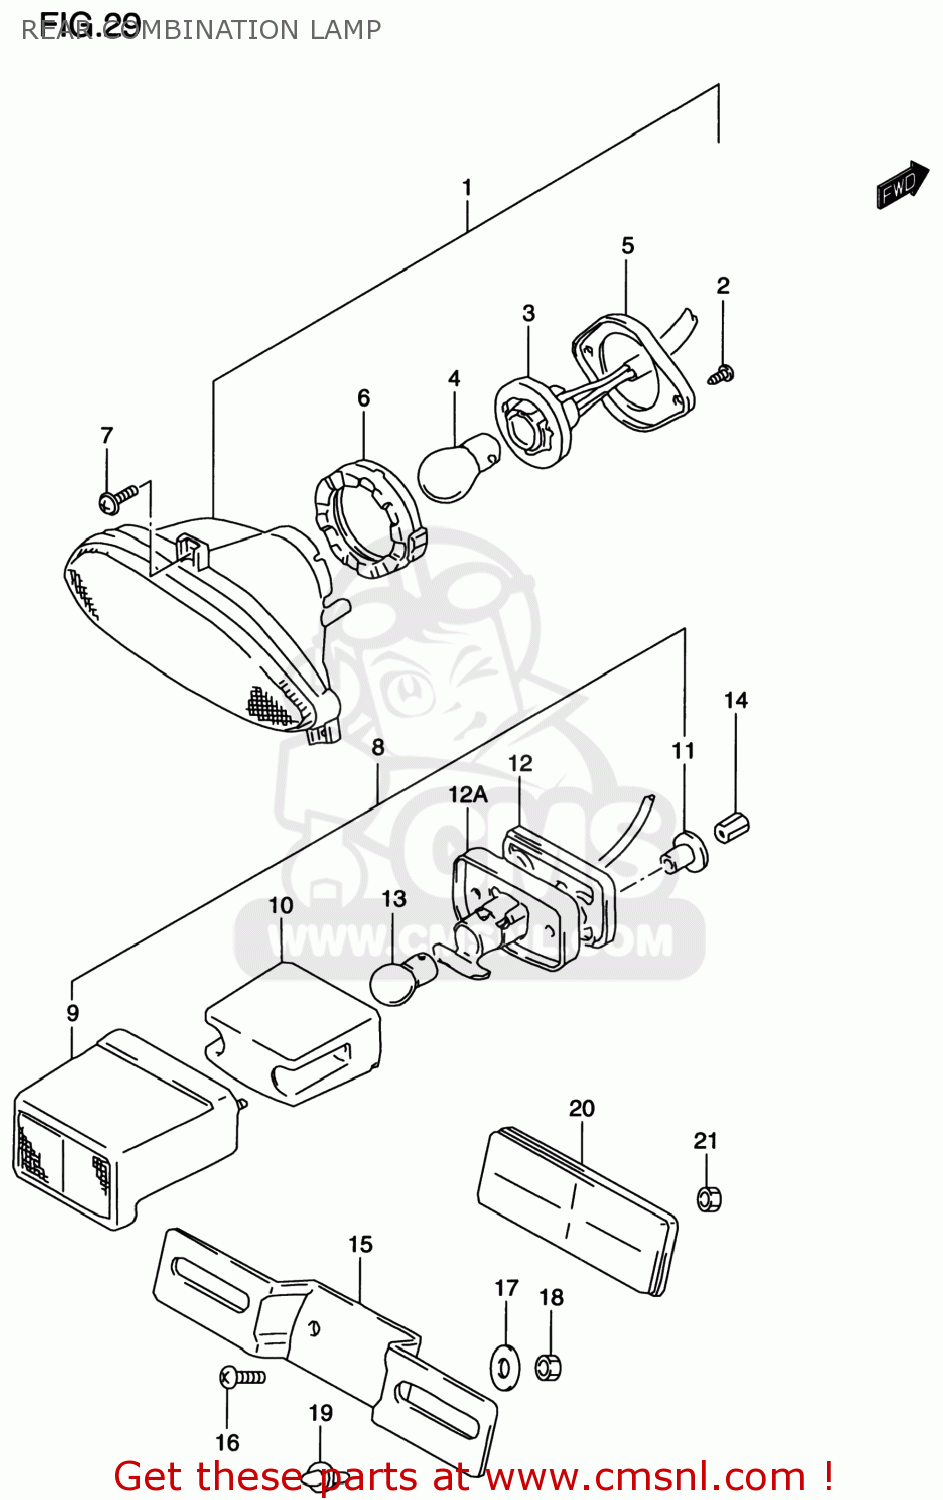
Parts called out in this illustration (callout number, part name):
1	LAMP ASSY,RR COMBINATION
2	SCREW
3	SOCKET & CORD
4	BULB(12V21/5W)
5	PLATE NO.2
6	CUSHION
7	TPG SCREW
8	LAMP ASSY,LICENSE PLATE
9	COVER,LICENSE
10	LENS
11	SPACER
12	CUSHION
12A	GASKET,LICENSE LAMP (NAS)
13	BULB(12V5W,BF150-40160A)
14	NUT
15	BRACKET,LICENSE PLATE
16	SCREW 6X12
17	WASHER(6.5X20X1.6)
18	NUT 6MM
19	CUSHION
20	REFLECTOR ASSY,RR
21	NUT
